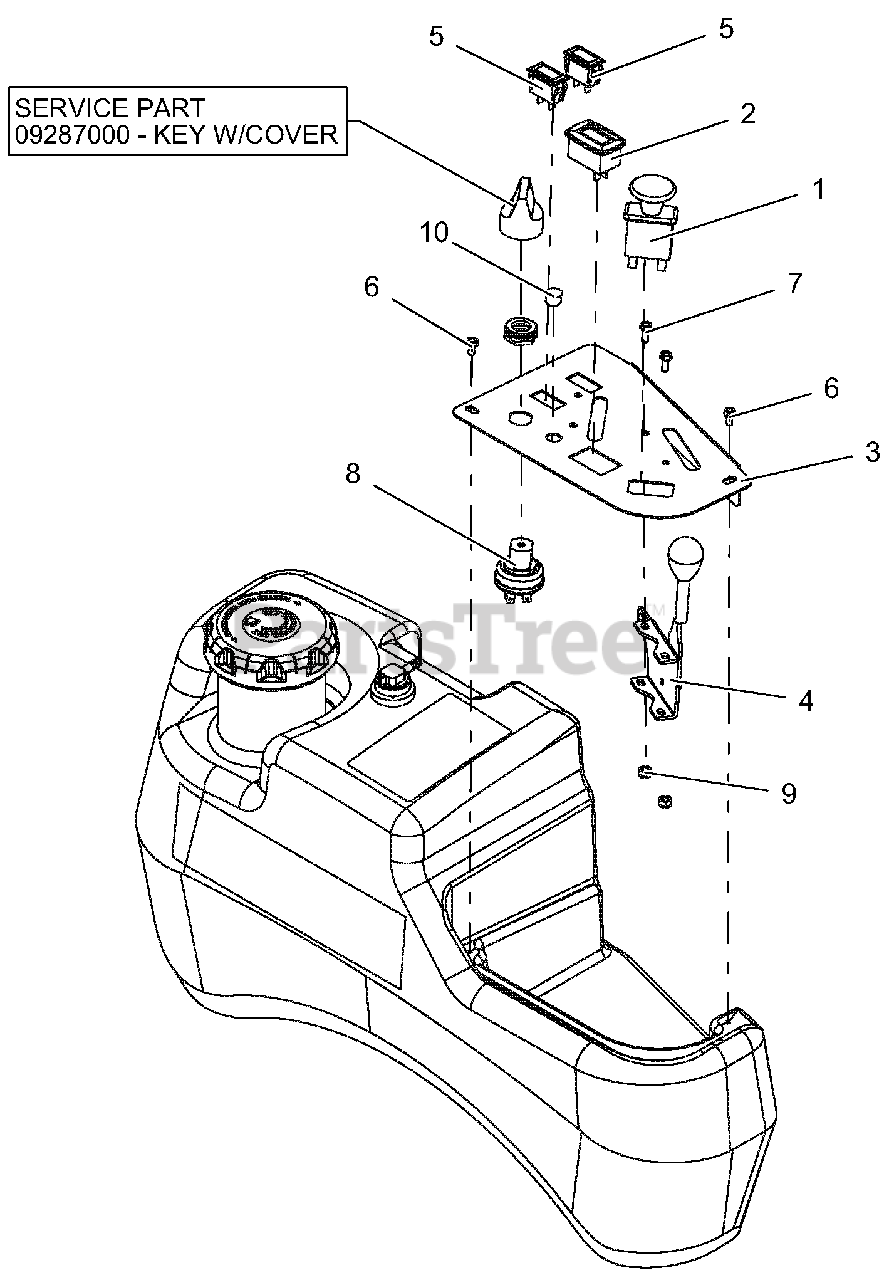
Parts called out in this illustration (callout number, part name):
1	SWITCH, CLUTCH
2	METER, HOUR W/MAINTENANCE
3	PANEL, CONTROL - PROTURN 100 (BLACK)
4	CABLE, THROTTLE
5	LIGHT, INDICATOR
6	SCR-MCH 10-24X.38 HWHSTAINLESS
7	@SCR-MCH 10-24X.50 HWH YWZC
8	SWITCH, IGNITION
9	NUT-LK-NYL #10-24 YWZC
10	PLUG, HOLE .50 DI A
